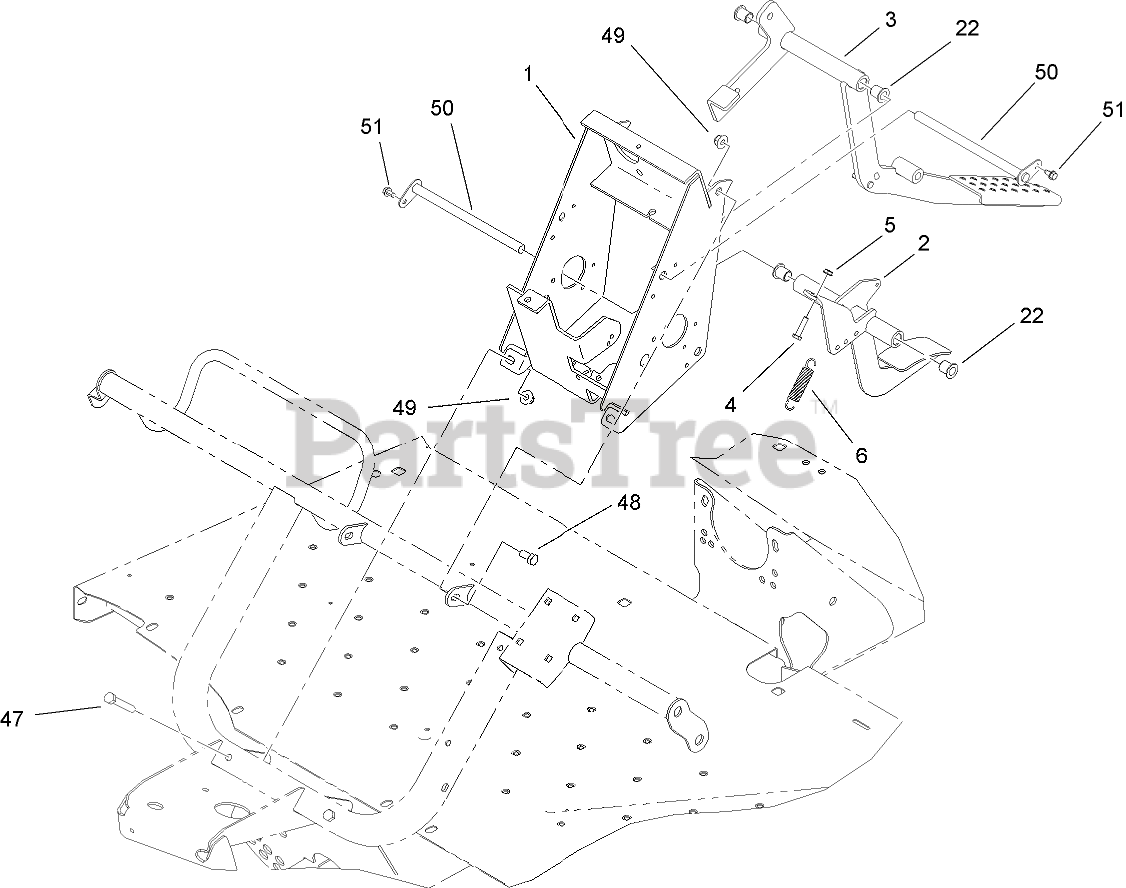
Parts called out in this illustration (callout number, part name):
1	PEDAL SUPPORT FRAME ASM
2	PEDAL-THROTTLE
3	Pedal-Brake
4	SCREW-HH
5	NUT-KEPS
6	SPRING-RETURN, PEDAL
22	BUSHING-FLANGE
47	SCREW-HH
48	SCREW-HH
49	NUT-HF, NI
50	PIVOT-PEDAL
51	SCREW
